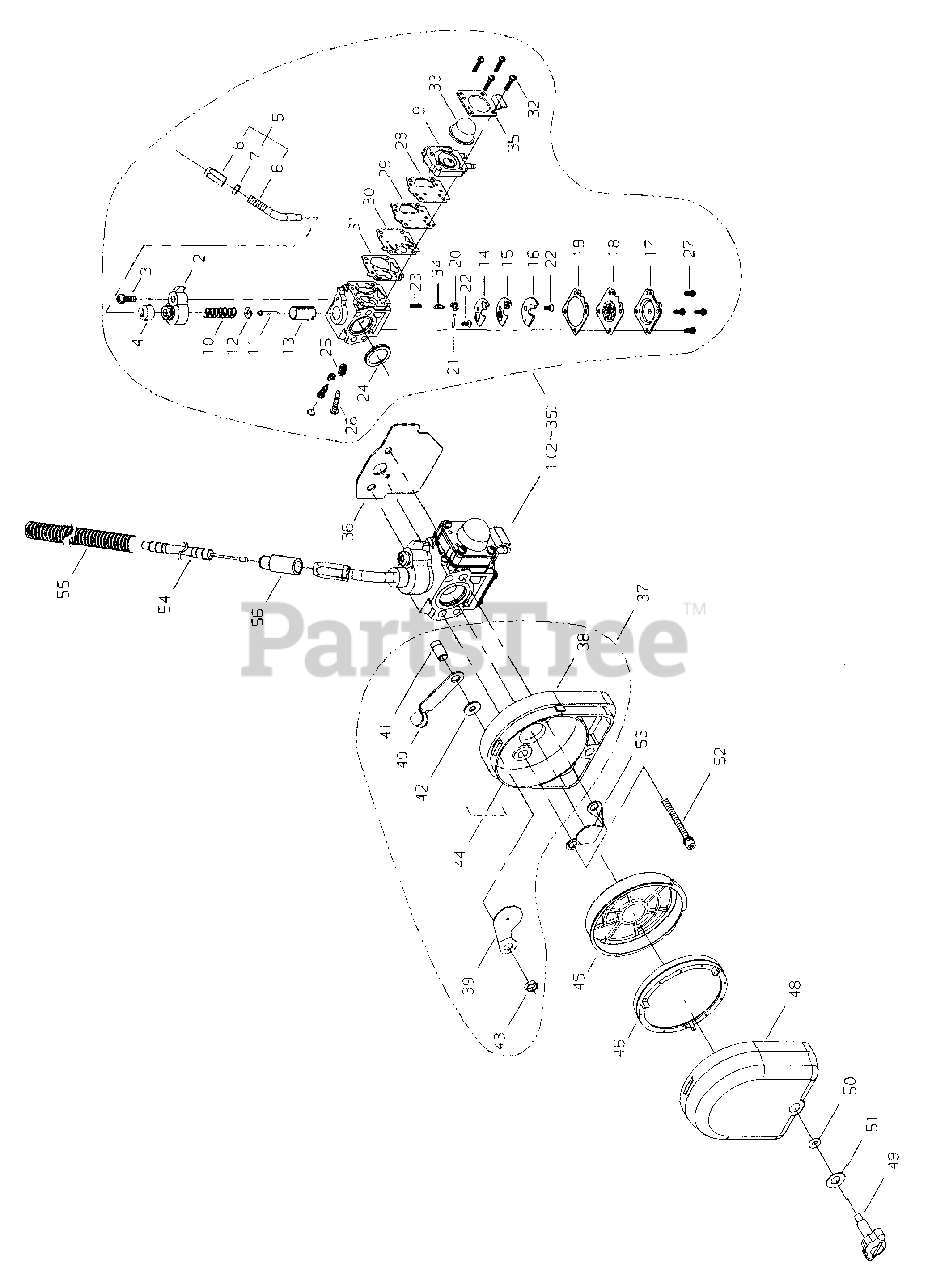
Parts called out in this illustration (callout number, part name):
1	CARBURETOR
2	CAP, CARBURETOR
3	SCREW - 5X15
4	GROMMET
5	CABLE ADJUSTER ASSY
6	CABLE ADJUSTER ASSY
7	LOCKNUT
8	NUT, CABLE ADJUST
9	BASE, PURGE
10	SPRING, THROTTLE
11	NEEDLE, JET
12	SEAT, SPRING
13	VALVE, THROTTLE
14	GASKET
15	VALVE, CHECK
16	PLATE
17	COVER, DIAPHRAGM
18	DIAPHRAGM, METERING
19	GASKET, METERING
20	LEVER, METERING
21	PIN, METERING LEVER
22	SCREW, METERING LEVER PIN
23	SPRING
24	SEAL
25	SPRING
26	SCREW, IDLE ADJUST
27	SCREW
28	GASKET, PUMP
29	PLATE, PUMP
30	DIAPHRAGM, PUMP
31	GASKET, PUMP
32	SCREW - 3X14
33	BULB, PURGE
34	VALVE, INLET NEEDLE
35	COVER, PUMP
36	GASKET, INTAKE
37	AIR FILTER CASE ASSY
38	CASE, AIR FILTER
39	PLATE, CHOKE
40	LEVER, CHOKE
41	SHAFT, CHOKE
42	WASHER - CONICAL
43	NUT - 6
44	LABEL - CHOKE
45	SCREEN, REAR AIR FILTER
46	FILTER, HEAVY DUTY AIR
48	COVER, AIR FILTER
49	THUMBSCREW
50	O-RING
51	WASHER - CONICAL
52	BOLT - 5X50
53	PLATE
54	CABLE, THROTTLE
55	TUBE, PROTECTIVE - CORRUGATED
56	CAP, CABLE
